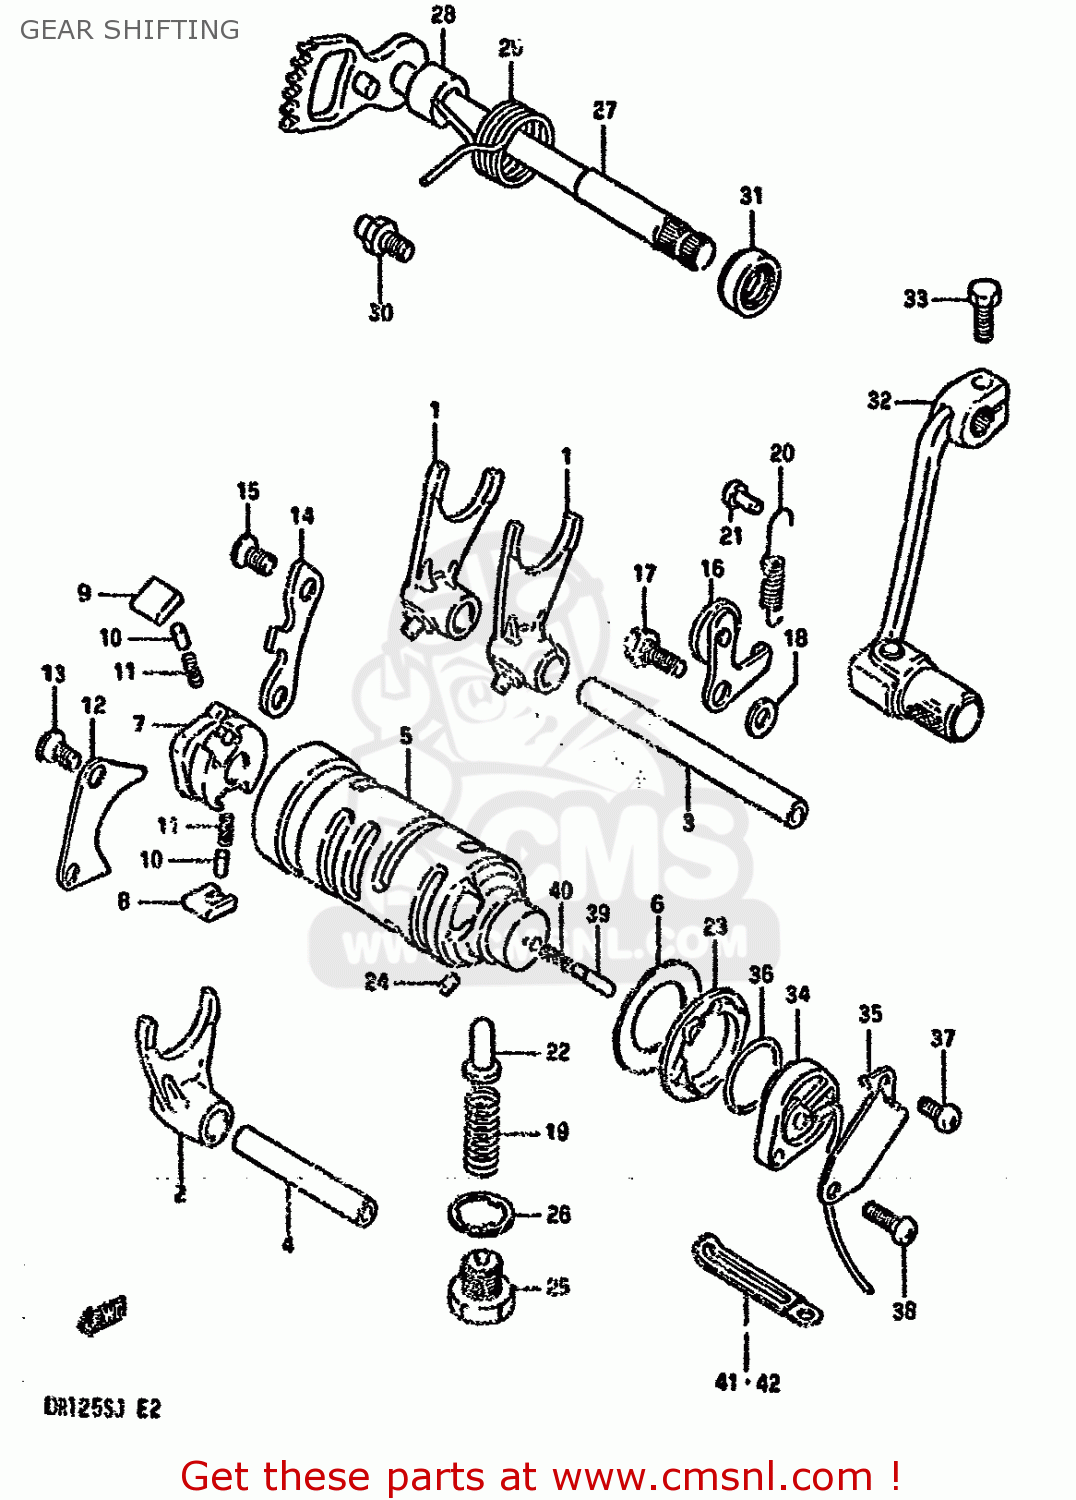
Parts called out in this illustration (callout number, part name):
1	FORK,GEAR SHIFT NO.1
2	FORK,GEAR SHIFT NO.3
3	SHAFT,GEAR SHIFT FORK(L:109)
4	SHAFT,GEAR SHIFT FORK
5	CAM,GEAR SHIFT
6	WASHER,THRUST
7	GEAR,GEARSHIFT CAM DRIVE
8	PAWL,GEAR SHIFT NO.1
9	PAWL,GEAR SHIFT NO.2
10	PIN(5X8)
11	SPRING
12	LIFTER,GEAR SHIFT POLE
13	SCREW
14	GUIDE,GEAR SHIFT CAM
15	SCREW
16	STOPPER,GEAR SHIFT CAM
17	BOLT
18	WASHER
19	SPRING
20	SPRING
21	RIVET
22	STOPPER,GEAR SHIFT CAM NO.2
23	PLATE,GEAR SHIFT CAM STOPPER
24	PIN 4X6
25	PLUG (14X12)
26	GASKET(14X19.2X2) (NAS)
27	SHAFT,GEAR SHIFT
28	SPACER(12X20X15.3)
29	SPRING
30	STOPPER,GEAR SHIFT CAM
31	OIL SEAL
32	LEVER ASSEMBLY,GEAR SHIFTING
33	BOLT
34	BASE ASSEMBLY,GEAR SHIFT TERMINAL
35	PROTECTOR,GEAR SHIFT SW
36	O-RING (D:2.4 ID:22.2)
37	SCREW
38	SCREW
39	PIN(5X15.5)
40	SPRING
41	CLAMP
42	CLAMP
